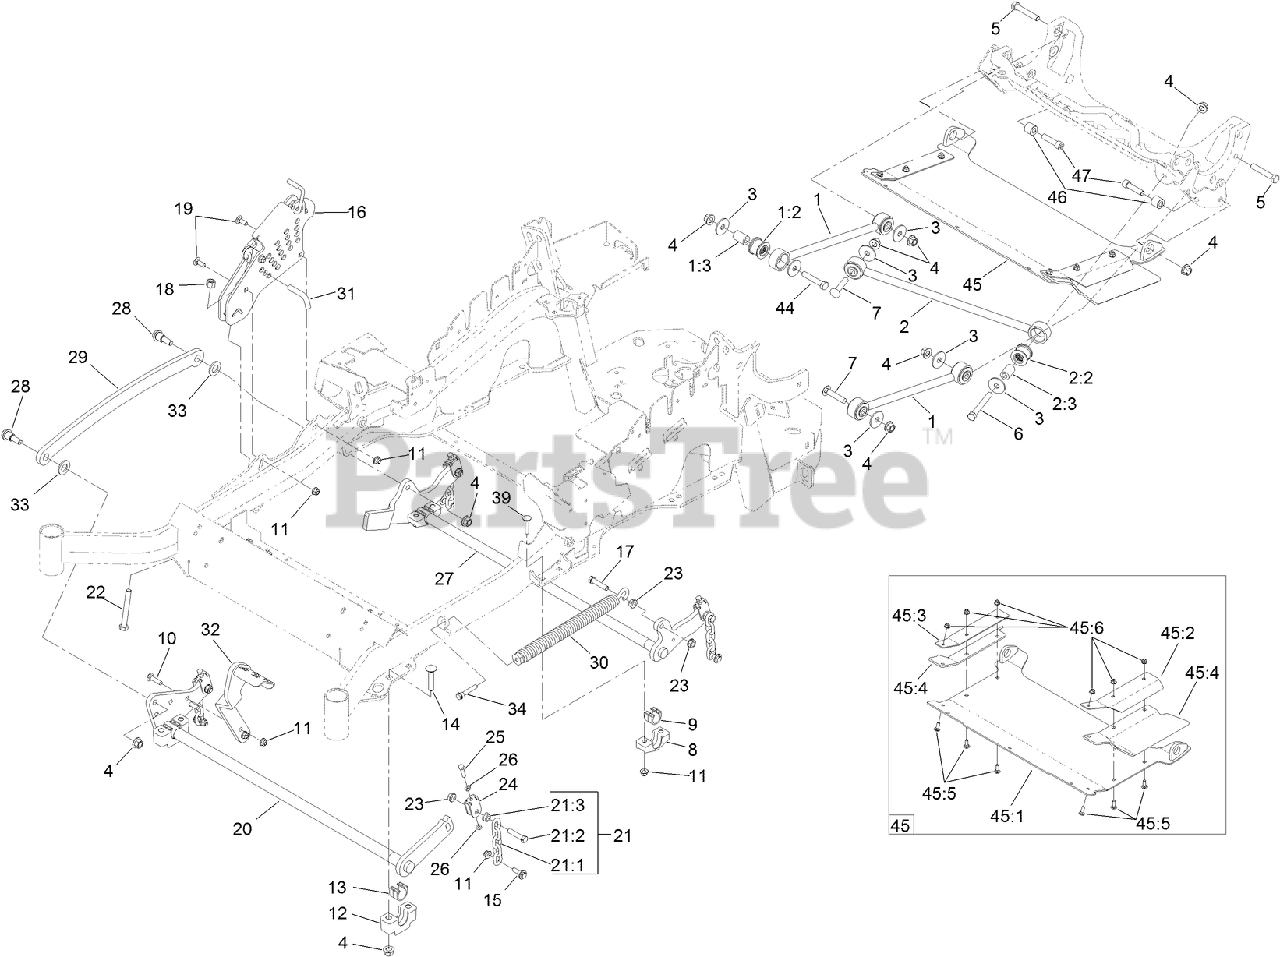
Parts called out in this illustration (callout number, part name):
1	DECK STRUT ASM
1:2	BUSHING-SUSPENSION, RUBBER
1:3	SPACER
2	PANHARD ROD ASM
2:2	BUSHING-SUSPENSION, RUBBER
2:3	SPACER
3	WASHER-THRUST
4	NUT-LOCK
5	SCREW-HH
6	SCREW-HH
7	SCREW-CARR
8	SUPPORT-CROSS SHAFT, REAR BEARING
9	BEARING-CROSS SHAFT, REAR
10	SCREW-CARR
11	NUT-HF, NI
12	SUPPORT-CROSS SHAFT, BEARING
13	BEARING-CROSS SHAFT, FRONT
14	BOLT-CARR
15	SCREW-SHOULDER, HHF
16	HOC ASM
17	SCREW-HH
18	NUT-LOCK, NI
19	BOLT-CARR
20	DECKLIFT-FRONT
21	DECK LIFT CHAIN ASM
21:1	CHAIN-LIFT, DECK
21:2	SCREW-HH
21:3	NUT-HF
22	BOLT-TAP
23	NUT-HF
24	YOKE-ADJUST, DECK
25	SCREW-HH
26	NUT-JAM
27	LIFT-DECK, REAR
28	SCREW-SHOULDER, HHF
29	LINK-LIFT, DECK
30	SPRING-EXTENSION
31	PIN-HOC
32	LEVER-FOOT
33	WASHER-FLAT
34	BOLT-SHOULDER
39	SCREW-CARR
44	SCREW-HH
45	DISCHARGE TUNNEL ASM
45:1	DISCHARGE TUNNEL ASM BLACK]
45:2	BRACKET-FLAP, LH
45:3	BRACKET-FLAP, RH
45:4	FLAP-RUBBER
45:5	SCREW-CARR
45:6	NUT-HF, NI
46	BUSHING-SLEEVE
47	SCREW-HSH
